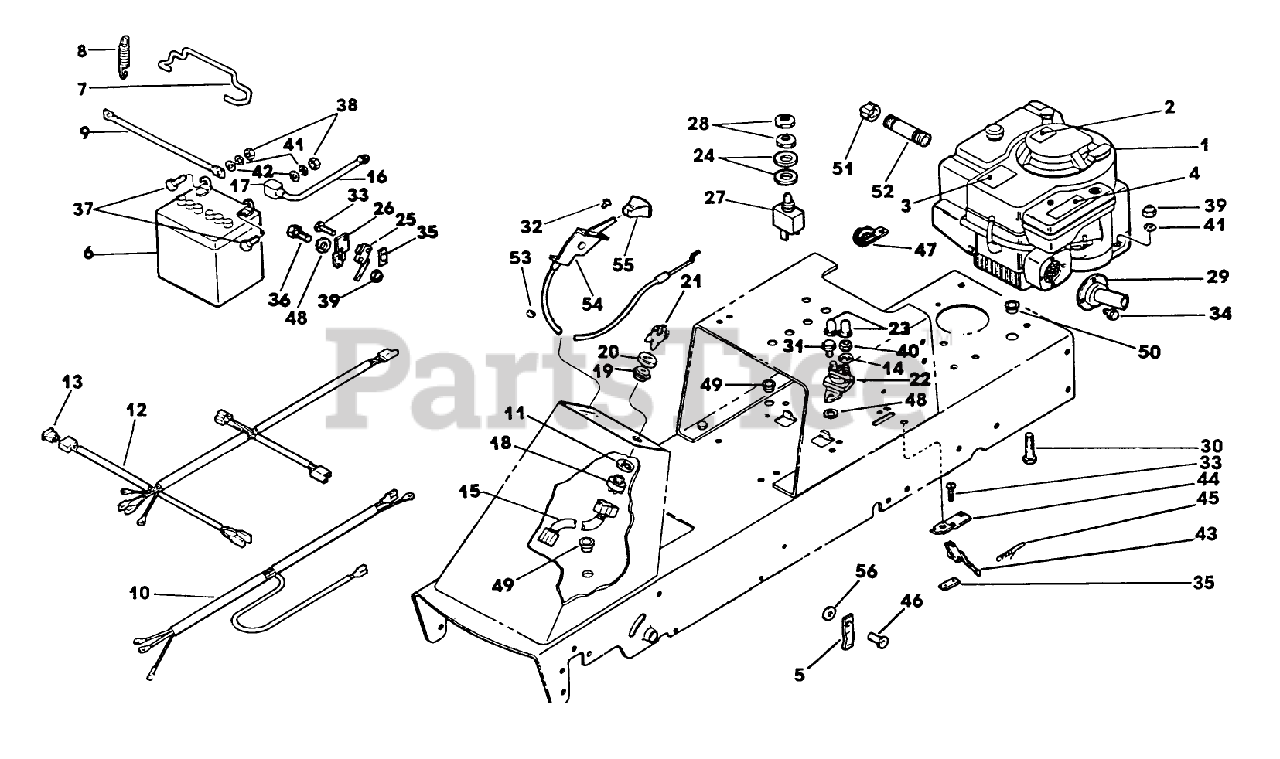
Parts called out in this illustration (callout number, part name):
7	ROD - BATTERY
8	SPRING
9	CABLE - GROUND
10	WIRING HARNESS
16	CABLE AY - POS.
19	NUT
20	BEZEL
21	KEY
22	SOLENOID
25	SWITCH
27	SEAT INTERLOCK SWITCH
31	SCREW-THREAD FRMG
32	SCREW - PPH
37	SCREW - HEX
38	NUT SS
39	NUT
40	NUT-HEX
50	BUSHING
55	THROTTLE KNOB
